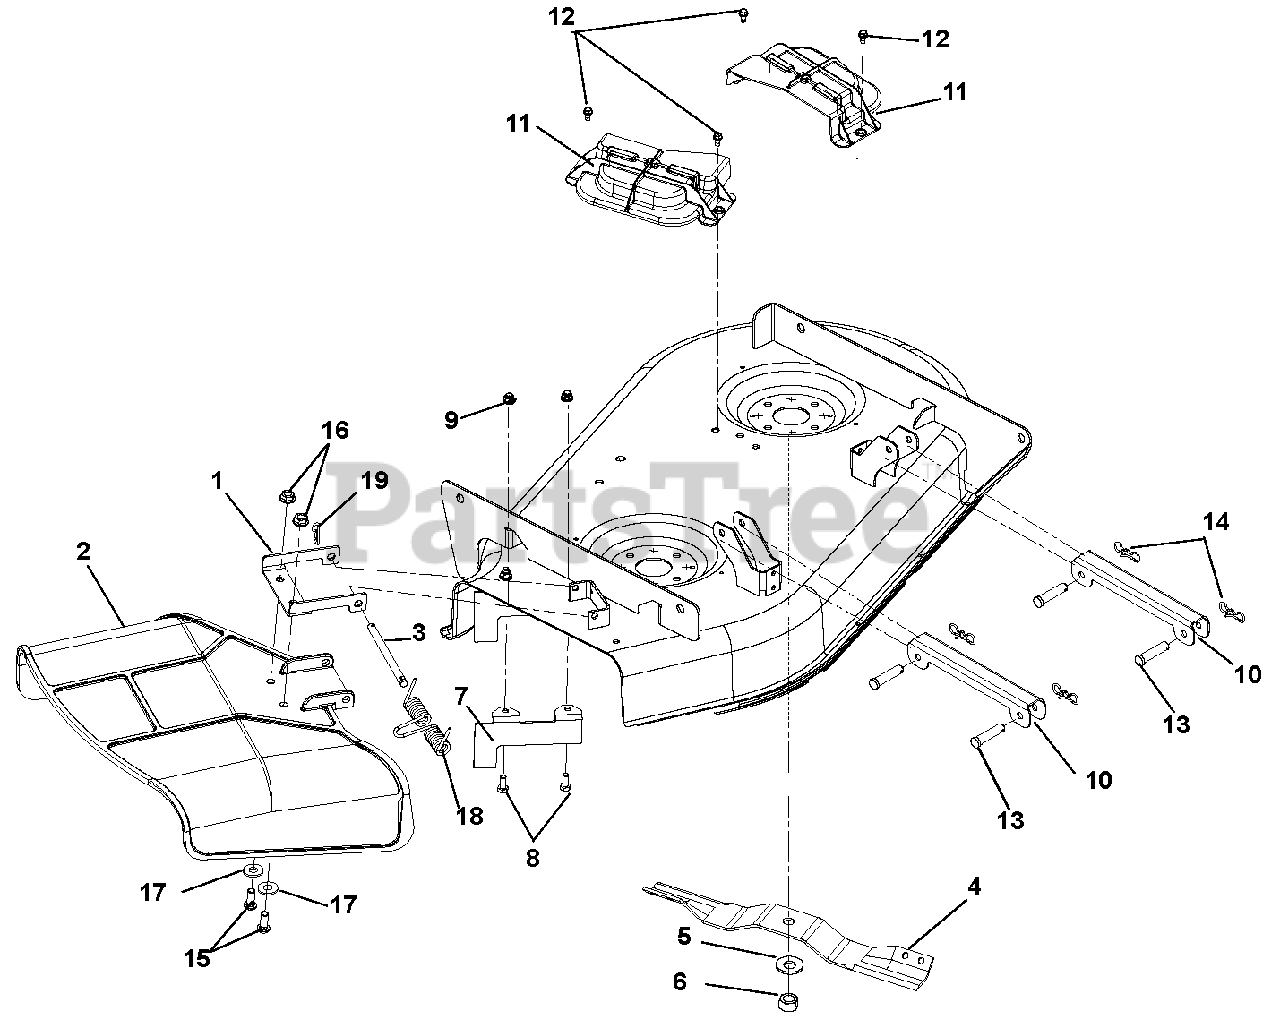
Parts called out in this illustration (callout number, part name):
1	Chute Reinforcement
2	Molded Chute
3	Pin, 5/16 x 3.88"
4	Blade, Mower 17.35
5	Washer, Beveled .63 x 1.625 x .14
6	Nut, Hex .62-18
7	Bracket, Baffle Discharge 34"
8	Bolt, Hex .31-18 x .75
9	Nut, .31-18 Nyloc Flange
10	Bracket, Stabilizer Link
11	Cover, Belt Molded
12	Screw, Tapping .25-20 x .50 Hex Washer Head
13	Pin, Clevis .375 x 2.00
14	Pin, Bow Tie Locking
15	Screw, .31-18 x .75
16	Nut, Locking Top Flange .31-18
17	Washer, Flat, Steel .38 x .875 x .083
18	Spring, Torsion
19	Pin, Hair .08 x .18 x 1.18
